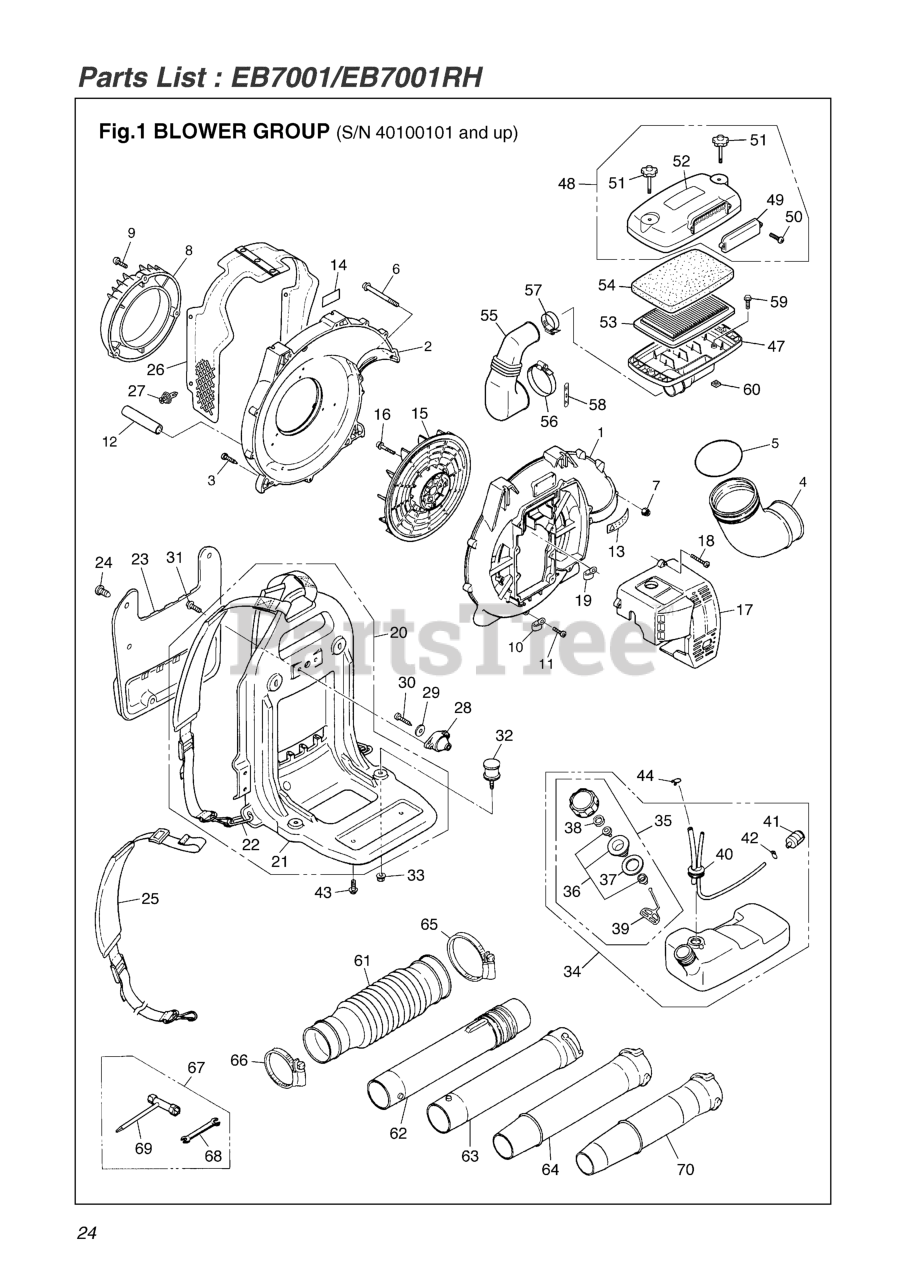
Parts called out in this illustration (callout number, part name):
1	CASE, VOLUTE
2	848-L5C-55B3
3	SCREW, M5 X 25
4	ELBOW
5	O-RING
6	SCREW, M5 X 70
7	NUT (B)
8	COVER, INLET
9	SCREW, M5 X 25
10	CLAMP (RPLS 1140-72231)
12	TUBE (RPLS. 07270-01507)
13	LABEL, CAUTION (RPLS -31910)
14	LABEL, NET
15	FAN
16	BOLT (RPLS 3405-12211)
17	COVER, ENGINE (RPLS -31611)
18	SCREW, M5 X 25
19	CLAMP
20	FRAME ASSY. (REPLACES -32001)
21	FRAME COMP. (RPLS -32100)
22	RING (REPLACES -21120)
23	PAD
24	CLIP (RPLS 3490-21320)
25	BAND ASSY (RPLS 2750- )
26	NET COMPLETE
27	CLIP
28	DAMPER, UPPER
29	WASHER
30	SCREW
31	BOLT, M5 X 16 (RPLS -32540)
32	DAMPER, LOWER
33	NUT, M6
34	TANK ASSY (RPLS. -85100)
35	CAP ASSY (RPLS -85201)
36	HOLDER (REPLACES -85230)
37	PACKING
38	FILTER
39	STOPPER
40	PIPE COMPLETE
41	FILTER ASSY
42	CLIP (REPLACES 2841-31280)
43	SCREW, M5 x 12
44	CLIP
47	BODY, CLEANER (RPLS -82110)
48	COVER ASSY. (EB7001)
49	COVER
50	SCREW, M5 X 25
51	BOLT, KNOB
52	LABEL, CLEANER
53	ELEMENT (PAPER)
54	ELEMENT (FOAM) (RPLS -82320)
55	HOSE
56	BAND
57	BAND
58	LABEL, CHOKE
60	NUT
61	HOSE
62	SWIVEL-JOINT (REPLACES -51200)
63	PIPE, STRAIGHT
64	PIPE, END
65	CLAMP
66	CLAMP (RPLS 3050-13230)
67	TOOL SET
68	SPANNER, 8 X 10 (RPLS 2540- )
69	WRENCH, SOCKET
70	KIT, NOZZLE (USE 2756-51221)
